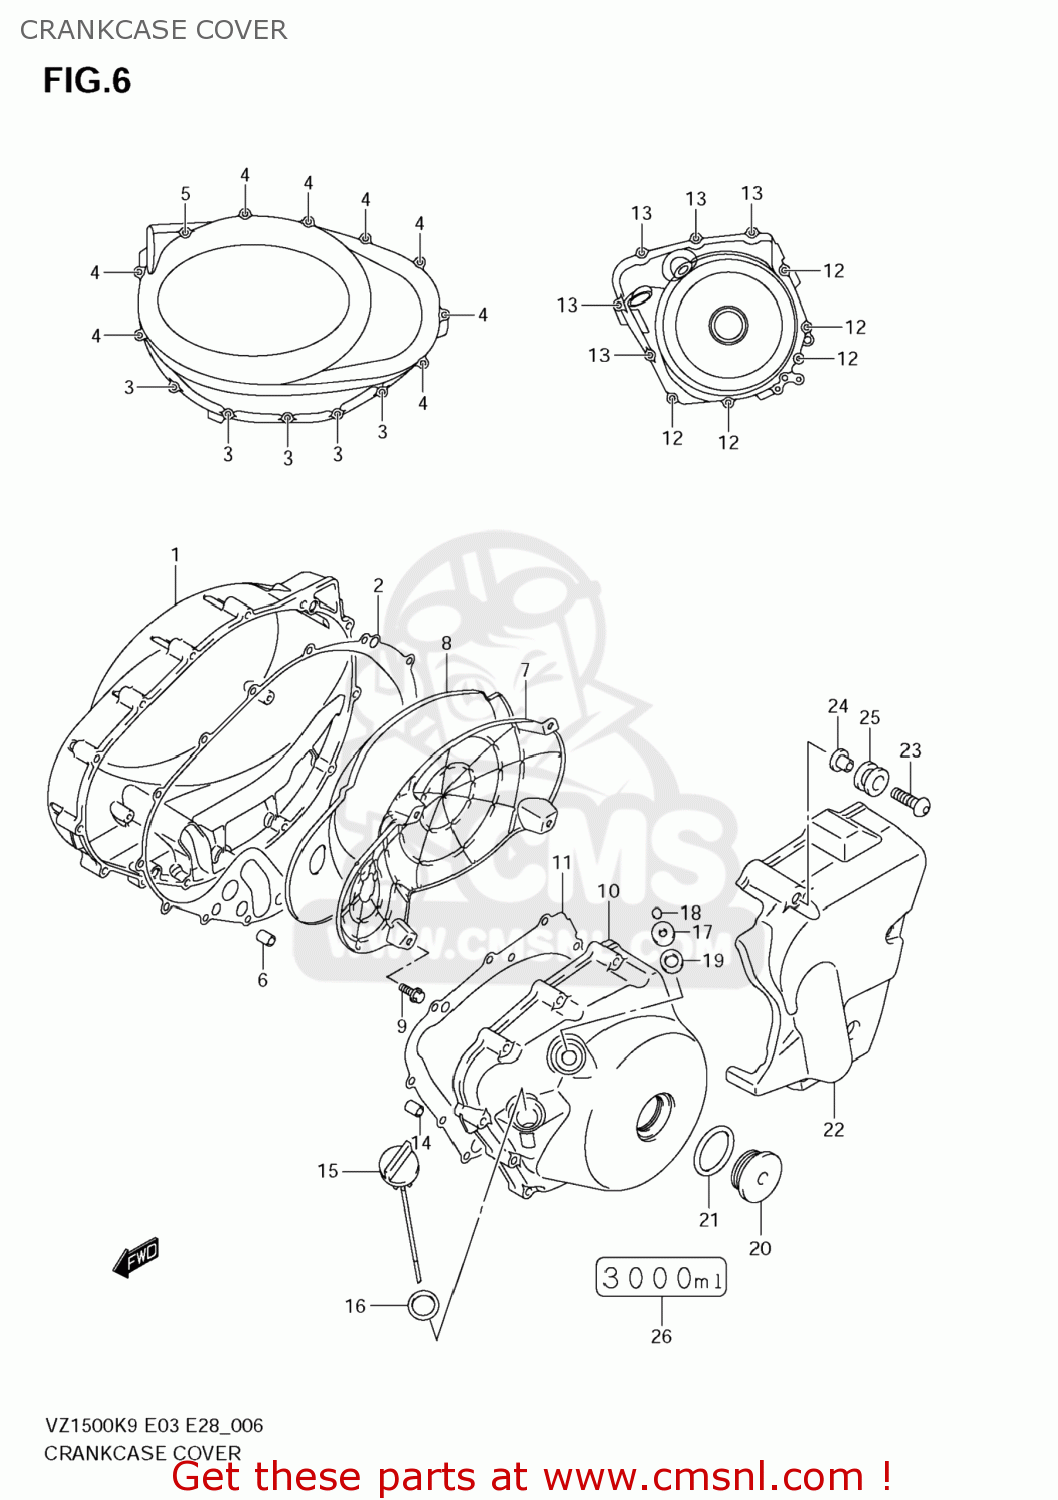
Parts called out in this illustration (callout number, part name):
1	COVER,CLUTCH
2	GASKET,CL COVER (NAS)
3	BOLT(6X30)
4	BOLT(6X40)
5	BOLT(6X50)
6	PIN
7	PLATE,CLUTCH COVER
8	DAMPER,CLUTCH COVER
9	BOLT
10	COVER,MAGNETO
11	GASKET,MAGNETO COVER (NAS)
12	BOLT(6X30)
13	BOLT(6X40)
14	PIN
15	GAUGE,OIL LEVEL
16	O RING(D:3.1,ID:16.8)
17	PLUG,14X12
18	CAP(OD:12)
19	GASKET(13.8X18.8X4.8) (NAS)
20	Chrome Crankshaft Plug
21	O RING(D:3.1,ID:32.7)
22	COVER,SECONDARY DRIVE UNIT
23	SCREW(6X20)
24	WASHER
25	CUSHION
26	NOTE,ENGINE OIL
